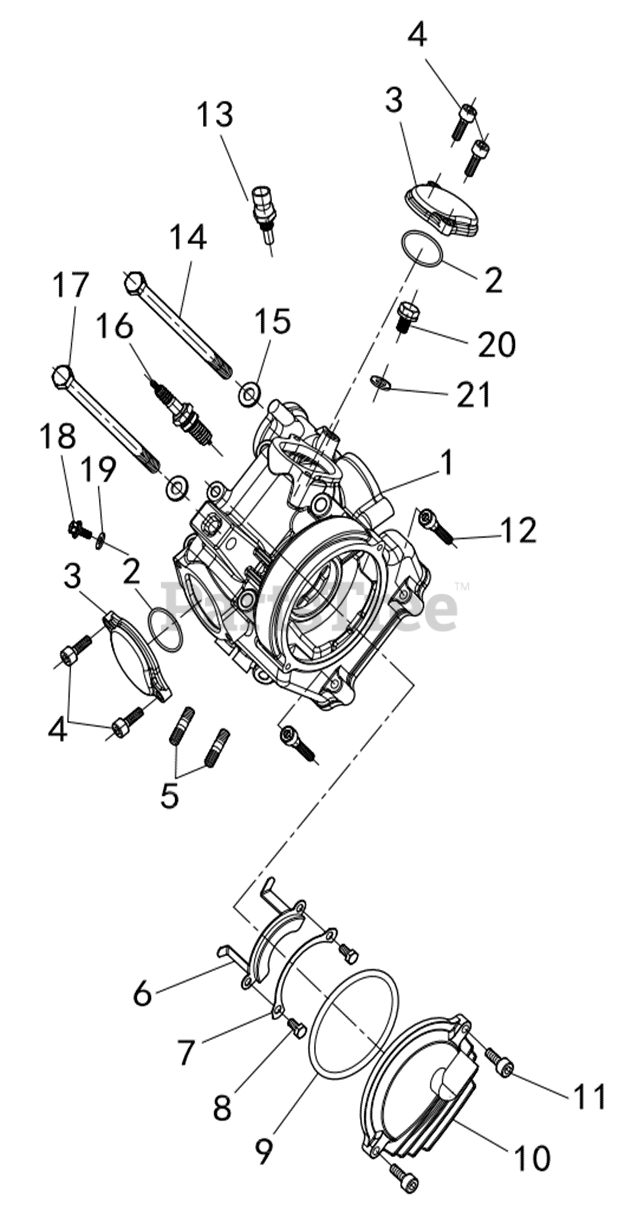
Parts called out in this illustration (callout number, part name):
1	CYLINDER HEAD ASSEMBLY
2	O-RING 58 x 2.4
3	VALVE COVER
4	HEX HEAD CAP SCREWM6X20
5	STUD M8X45
6	CAM BEARING HOLDER
7	BOLTS - SPACING PLATE
8	BOLTS HEXAGON HEAD M6 x 16
9	O-RING 107 x 2.4
10	CAMSHAFT COVER
11	BOLTS HEXAGON FLANGE M6 x 25
12	HEX HEAD CAP SCREW M8X40
13	3 WIRE TEMP SENSOR
14	BOLTS CYLINDER M10X 1.25 x 261
15	COPPER WASHER 10x18x2
16	SPARK PLUG - NGK DR8EA
17	BOLT CYLINDER M10 x 1.25 x 230
18	HEX FLANGE BOLT M6X12
19	ALUMINUM WASHER 6X12X1.5
20	HEX FLANGE M12-1.5:15
21	FLAT WASHER
